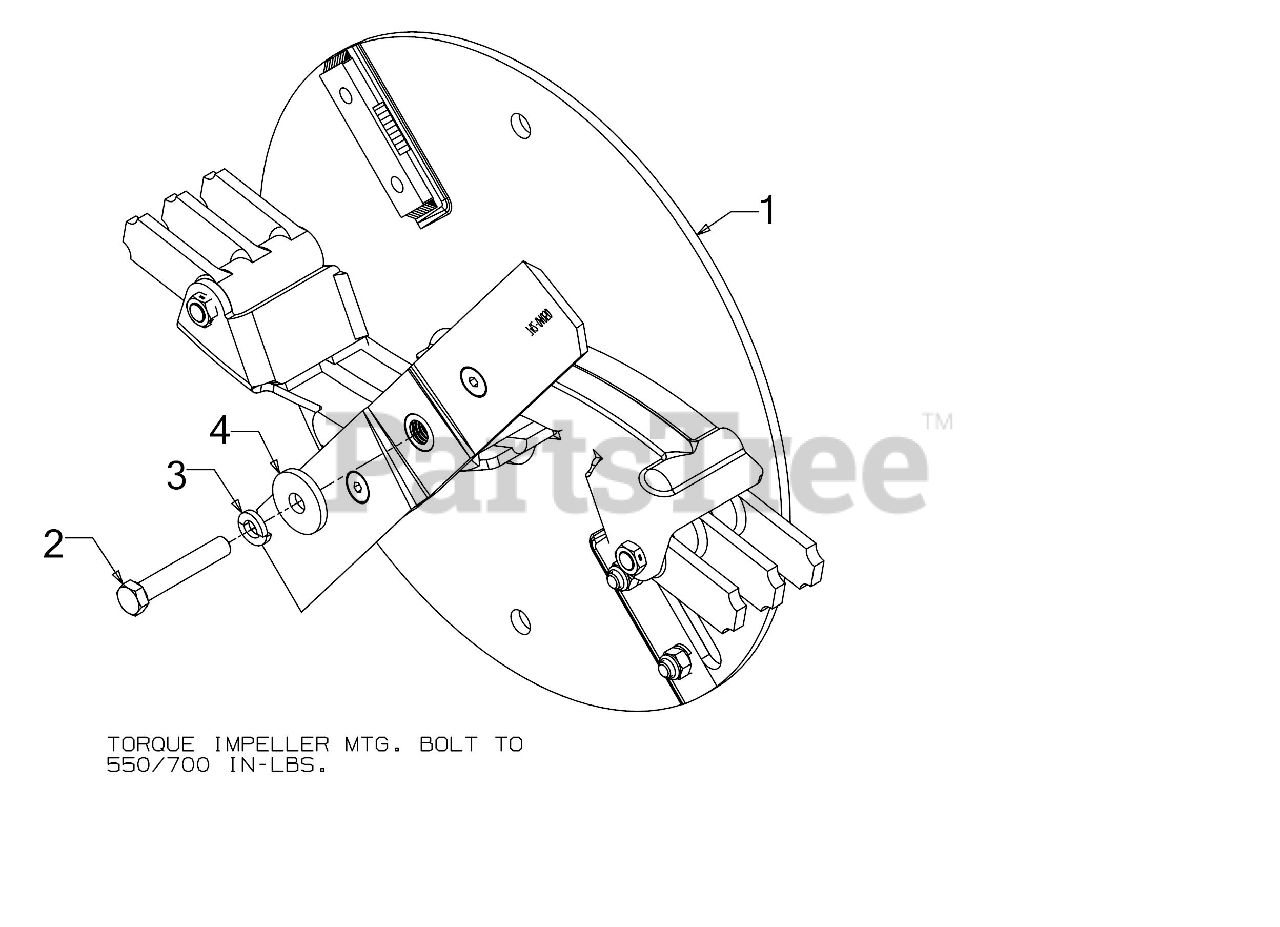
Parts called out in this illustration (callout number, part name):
1	IMPELLER ASSEMBLY
2	SCREW 3/8-24X2.25 GR8
3	LOCK WASHER 3/8HD
4	FLAT WASHER
